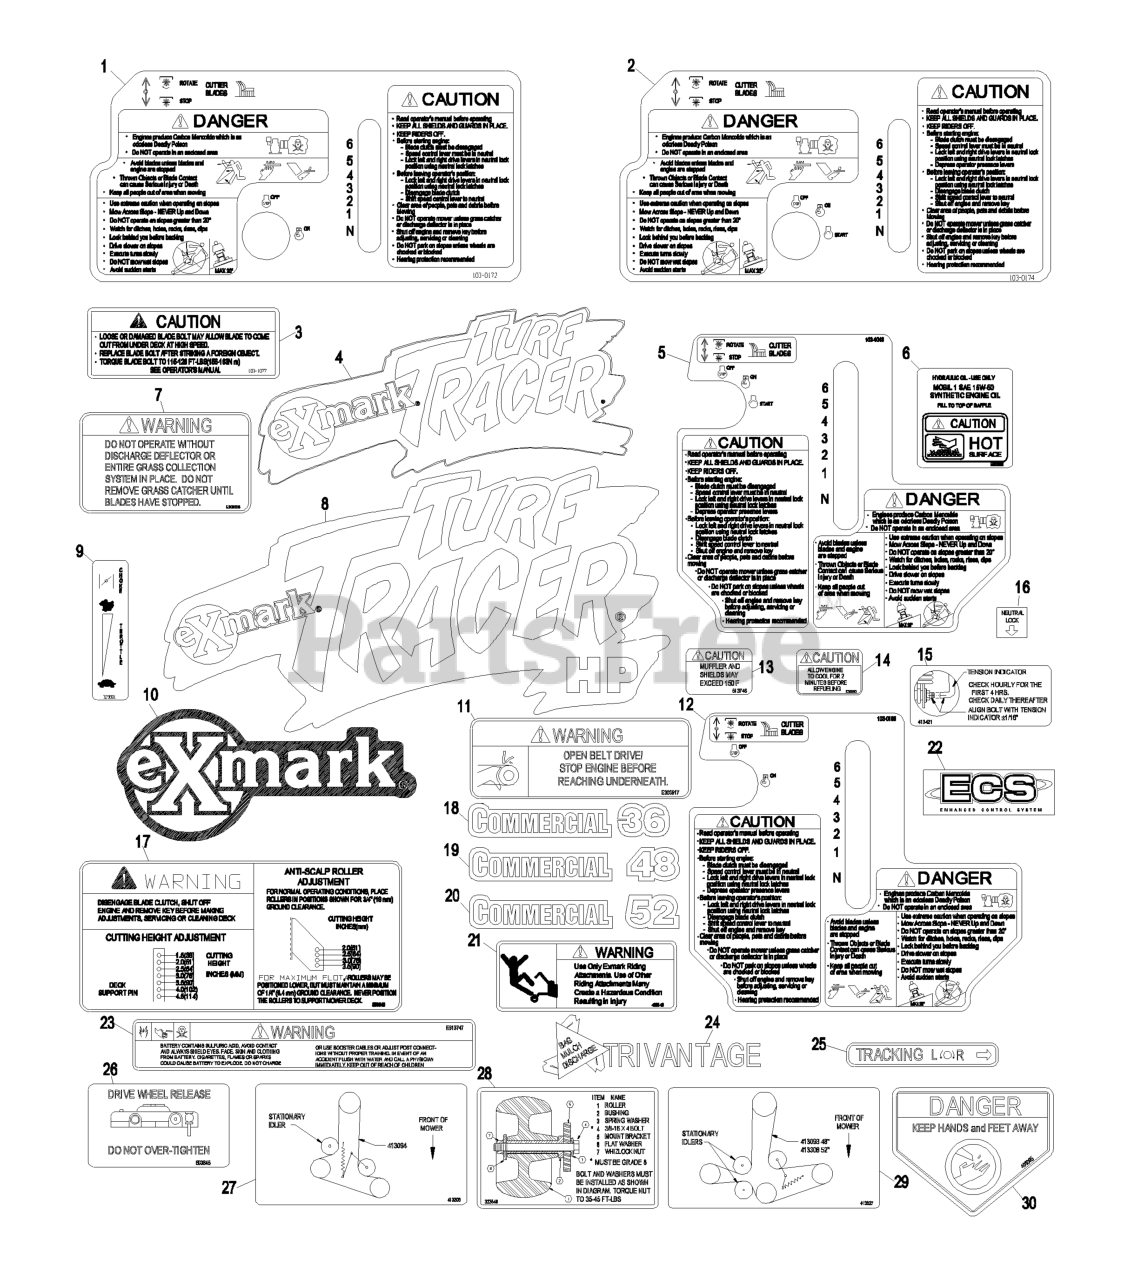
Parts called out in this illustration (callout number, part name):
3	DECAL,BOLT TORQUE
7	DECAL-WARNING, DISCHARGE
9	DECAL,THROTTLE
11	DECAL,BELT DRIVE
15	DECAL,INDICATOR
16	DECAL,NEUTRAL LOCK
17	DECAL,ANTI SCALP
18	DECAL,COMMERCIAL 36
19	DECAL,COMMERCIAL 48
20	DECAL,COMMERCIAL 52
21	DECAL,SULKY WARNING
23	DECAL-BATTERY
25	DECAL,TRACKING ADJUST
26	DECAL,DRIVE RELEASE
27	DECAL,BELT ROUTING
28	DECAL,ROLLER MOUNTING
29	DECAL,BELT ROUTING
30	DECAL-DANGER
